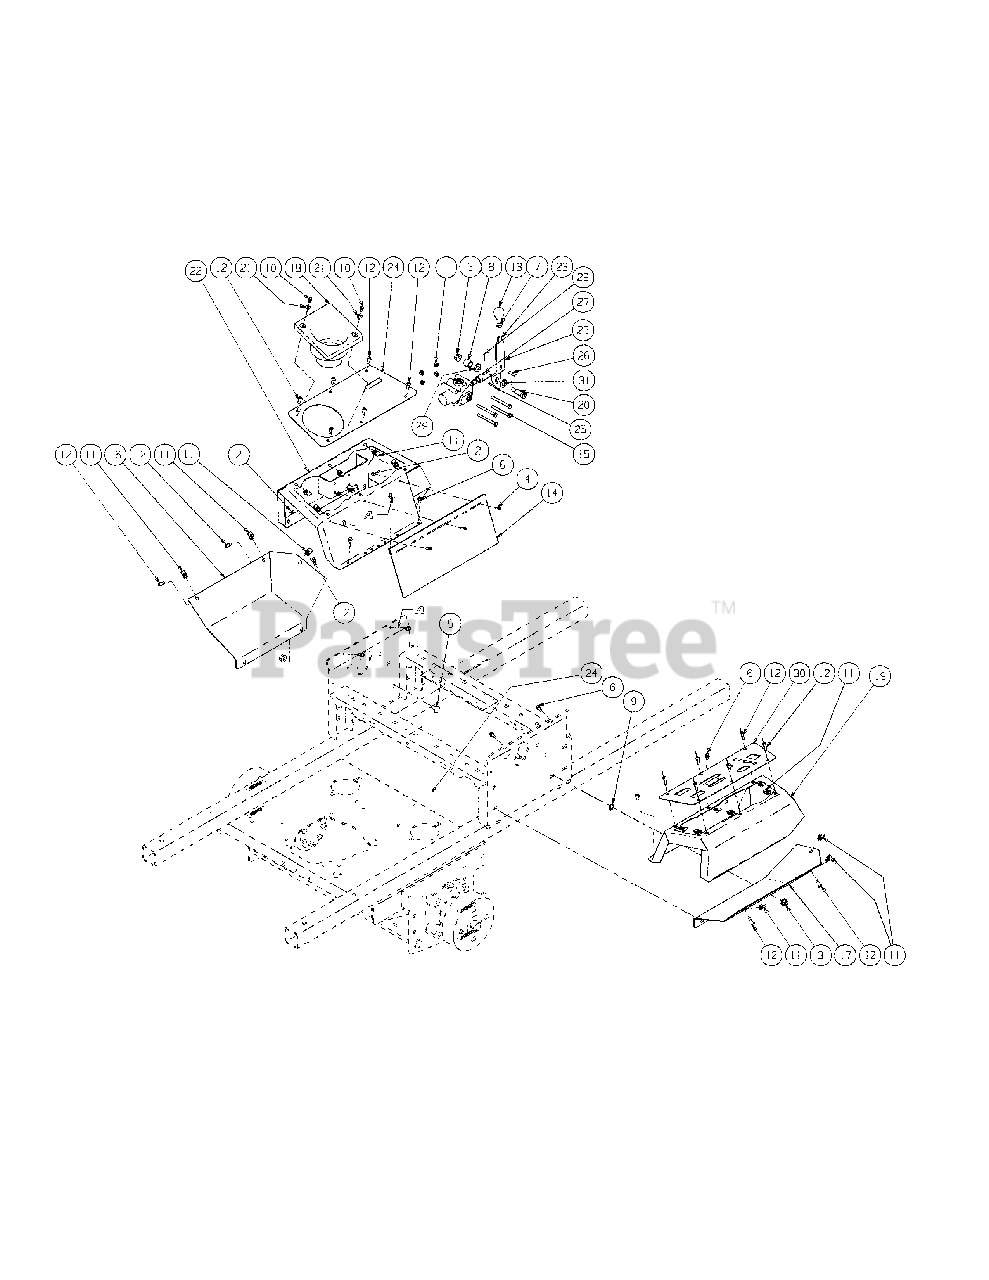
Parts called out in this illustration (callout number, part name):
1	Lock Nut w/Nylon Insert
2	Lock Nut, Nylon Insert, 10-32
3	Flange Lock Hex Nut, 3/8-16
4	Phillips Head Machine Screw, 10-32 x 5/8
5	Carriage Bolt, 3/8-16 x .75
6	Screw, TT, 1/4-20, 0.5, Hex Index Washer
7	Nut, 3/8-16, Jam
8	Spacer, .510 x .75 x .700
9	Push Retainer, 3/8
10	Screw, #10-32 x 0.500
11	U-Nut, 1/4-20
12	Capscrew, 1/4-20 x .750
13	Knob, 3/8-16
14	Bag, Debris Storage
15	HHCS, 1/4-20 x 2.75
16	Lower Panel, LH
17	Lower Panel, RH
18	Cup Holder
19	Control Panel, RH
20	Shoulder Bolt, 1/2 x 1.00, 3/8-16
21	Washer, 3/16
22	Control Panel, LH
23	Lift Valve Bracket
24	Control Panel Cover, LH
26	Pin, .25Dia. x .9375 LG
28	Cotter Pin, 1/16 x .75
29	Washer, .536 ID x .930 OD x .05
30	Control Panel Cover, RH
31	Washer
